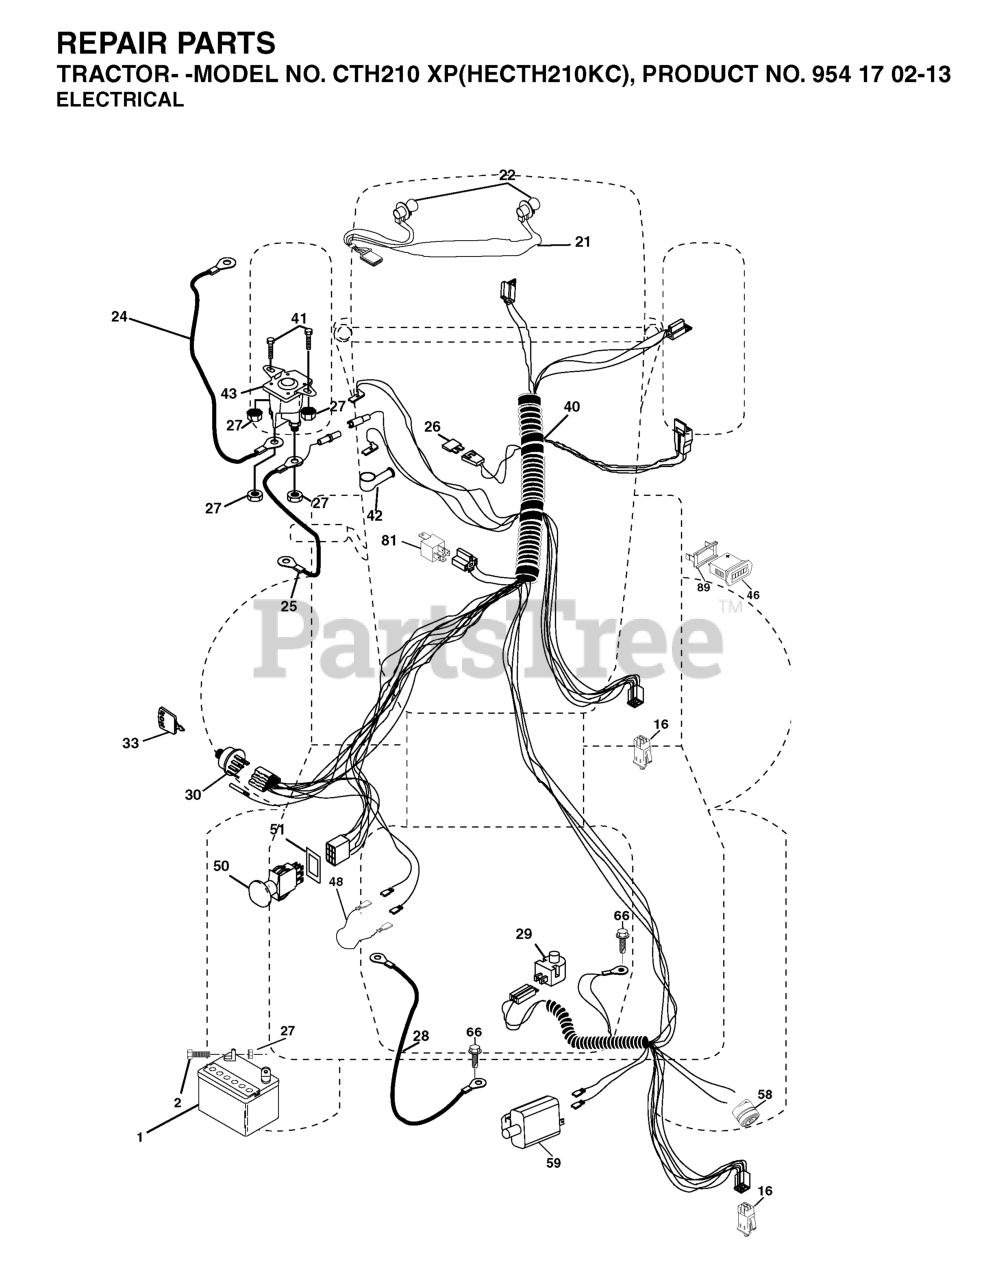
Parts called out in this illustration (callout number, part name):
1	BATTERY 12V .35 AMP
2	BOLT.HEX.1/4.X.3/4.DICHROMATE
16	SWITCH INTERLOOK PUSH-IN
21	HARNESS.W/LIGHT SOCKET
24	BATTERY CABLE
25	CABLE BATTERY
26	FUSE 20AMP
27	NUT
28	CABLE GROUND
29	RP.SWITCH.PLUNGER.NC.GRAY
30	IGNITION SWITCH
33	KEY MLD GEN DELTA
41	BOLT
42	TERMINAL COVER
43	SOLENOID
46	HOUR METER
48	ADAPTER.AMMETER
50	RP.PTO.SWITCH.8 TERMINAL.BLACK
51	FRAME RETAINING RING
58	BUZZER
59	.WITCH.FULL BAGGER.INDICATOR
81	RELAY.ASSY.T
89	BRACKET SNAP-IN HOURMETER
